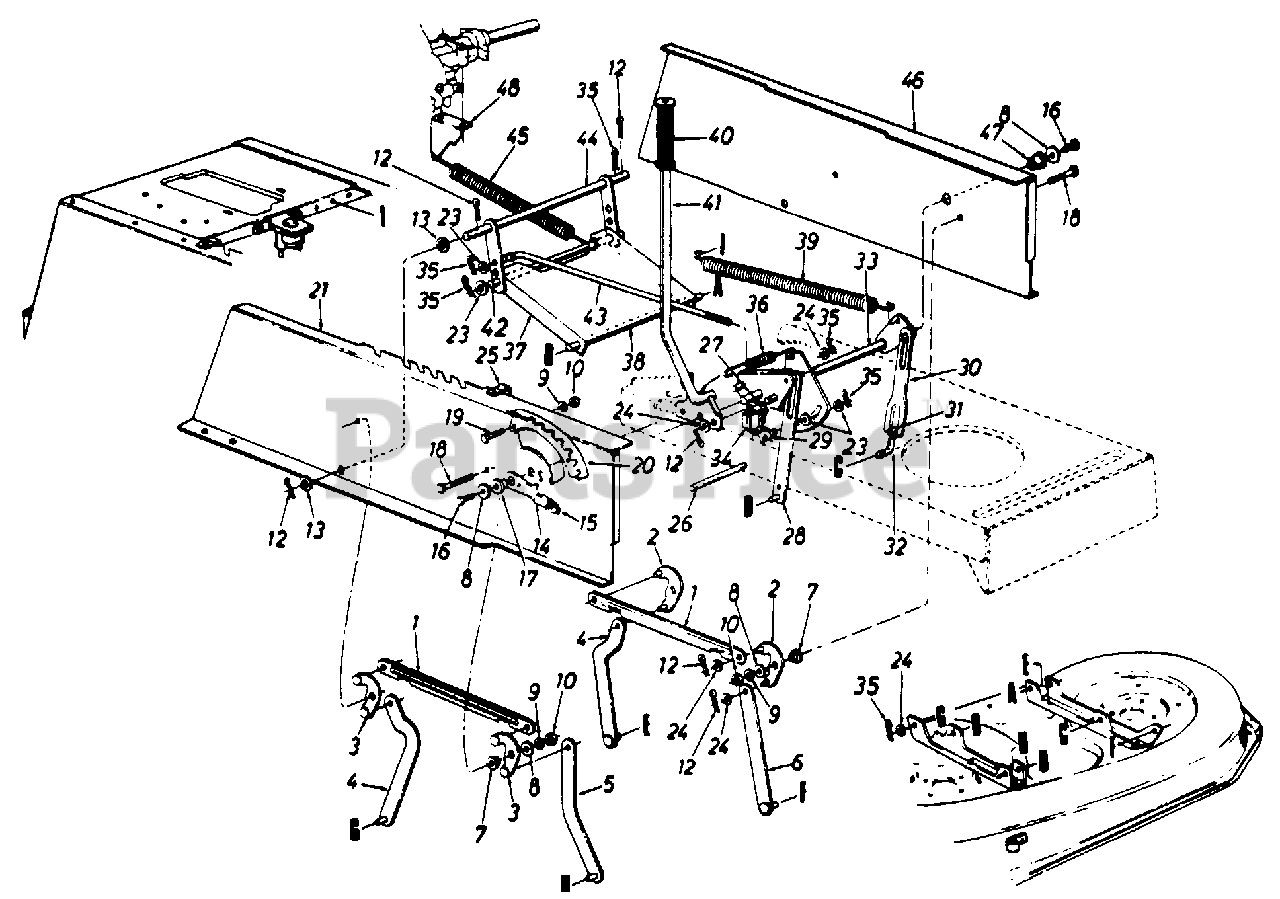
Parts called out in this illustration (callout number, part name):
1	Connecting Rod
2	Pivot Link Ass'y. - L.H.
3	Pivot Link Ass'y. - R.H.
7	Shld. Spacer .318" I.D.
8	Fl-Wash. .344" I.D. x .62" O.D.
9	L-Wash. 5/16" I.D.
10	Hex Nut 5/16-18 Thd.
12	Cotter Pin 1/8" Dia.
13	Fl-Wash. .635" I.D. x 1.0" O.D.
14	Deck Lift - Down Stop
16	Hex Wash. TT-Tap Scr. 5/16-18 x .75" Lg.
17	Flange Brg. .63" I.D.
18	Hex Wash. Hd. Scr. 5/16-18 x .875" Lg.
19	Hex Bolt 5/16-18 x .75" Lg.
20	Index Brkt.
21	Upper Frame - R.H.
23	Fl-Wash. .385" I.D. x .87" O.D.
24	Fl-Wash. .531" I.D. x .93" O.D.
26	Running Board Rod
27	Hex Wash. Hd. Tap Scr.
31	Hex Nut 1/2-20 Thd. (Gr. 5)
32	Lift Link Adjuster
35	Inter. Cotter Pin 3/8" Dia.
36	Extension Spring
37	Stabilizer Bracket
38	Shaft 1/2" Dia. x 10.28" Lg.
39	Extension Spring
40	Grip (Lift Handle)
41	Deck Lift Handle Ass'y.
42	Shaft 3/8" Dia. x 9.34" Lg.
43	Disengagement Rod
44	Stabilizer Shaft Ass'y.
45	Extension Spring 7.58" Lg.
46	Upper Frame - L.H.
47	Flange Brg. .632" I.D.
48	Spring Retainer Brkt.
